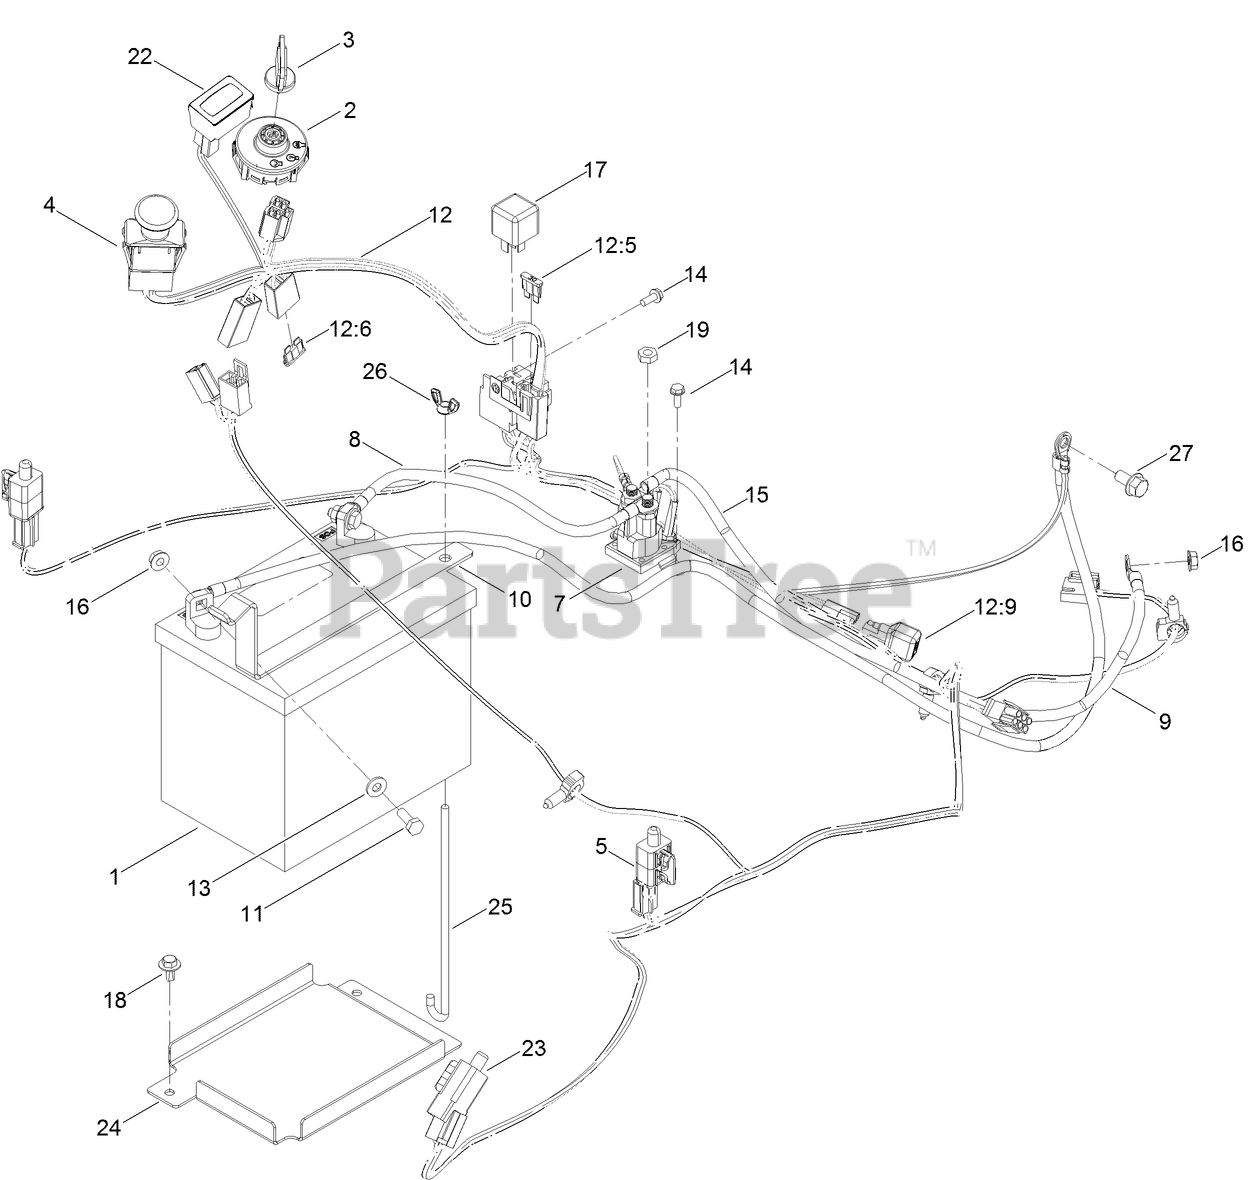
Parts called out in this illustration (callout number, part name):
1	BATTERY
3	KEY-IGNITION
4	SWITCH-PTO
5	SWITCH
7	SOLENOID
8	CABLE-BATTERY, POSITIVE
9	CABLE-BATTERY, NEGATIVE
10	STRAP-BATTERY
11	SCREW-HH
12	HARNESS-WIRE
12:5	FUSE-BLADE, 30 AMP
12:6	FUSE-BLADE, 25 AMP
13	WASHER-FLAT
14	SCREW-TAPTITE
15	WIRE-21 INCH
16	NUT-HF
17	RELAY
18	SCREW-HHFTF
19	NUT-JAM
22	HOURMETER
23	SWITCH-REVERSE
24	TRAY-BATTERY
25	BOLT-HOLDDOWN
26	WINGNUT
27	SCREW-HHF
